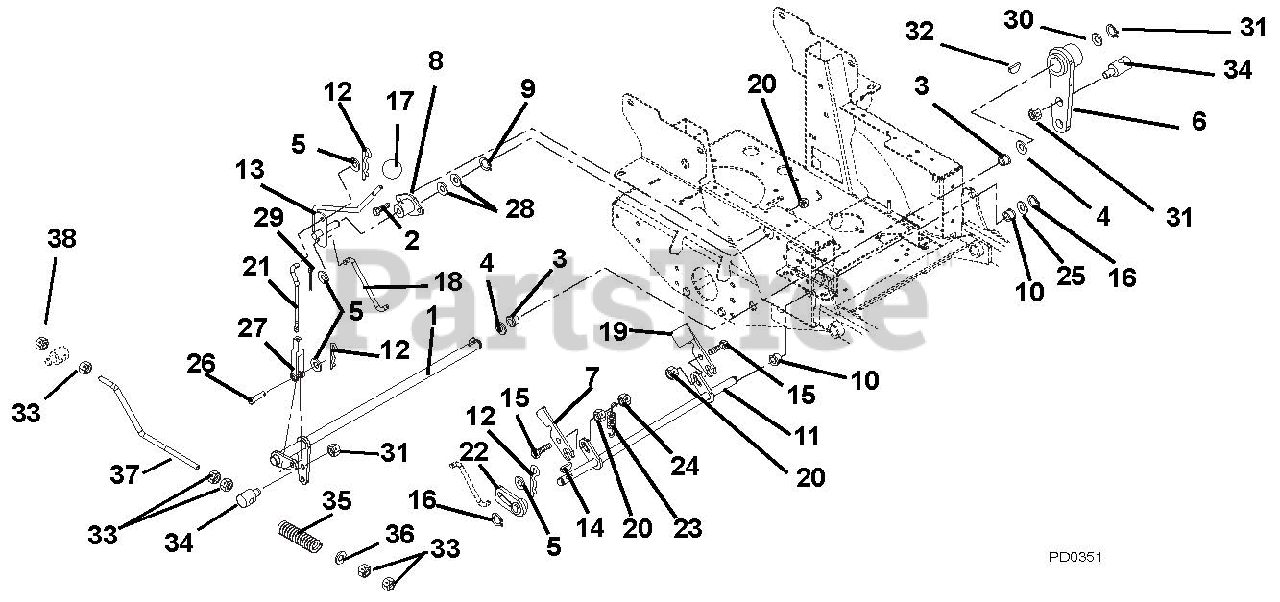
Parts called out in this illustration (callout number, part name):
1	Weldment, Brake Pivot
2	Bolt, Hex .31-18 x 1.00 Grade 5
3	Bushing, Flange .762 x 1.00 x .58 x 1.48 Nylon
4	Washer, Flat Steel .812 x 1.50 x .135
5	Washer, Flat Steel .406 x .812 x .065
6	Weldment, Brake Arm
7	Slide, Interlocking Brake
8	Bushing, Flange
9	Ring, Retaining External .625 x .05
10	Bushing, Flange .50 x .75 x .75 x 1.00
11	Weldment, Mechanical Brake
12	Pin, Hair
13	Weldment, Brake Actuating
14	Key, Woodruff .13 x .63
15	Bolt, Round Head Square Neck .31-18 x 1.25 Grade 5
16	Ring, Retaining External .50 x .05
17	Knob, Steering Lock
18	Linkage, Brake Actuating
19	Interlock, Safety Switch
20	Nut, Nyloc Flange 5/16-18
21	Linkage, Brake Compact-Z
22	Weldment, Parking Brake Hub
23	Spring, Tension .061 x .50 x 3.0
24	Nut, Locking Center .31-18
25	Washer, Flat Steel .505 x 1.00 x .062
26	Pin, Clevis .38 x 1.25
27	Clevis, .38-24 Adjustable
28	Washer-Flat-Steel .630 x 1.250 x .062
29	Pin, Cotter .09 x .75 Extended Prong Square Cut
30	Washer-Flat-Steel .755 x 1.375 x .062
31	Nut, Center Lock Jam Nut, .31-18
32	Key-Woodruff .19 x .75
33	Nut, Jam .375-24
34	Pin, Pivot
35	Spring, Compression .143 x .710 x 2.00
36	Washer, Flat Steel .406 x .812, .065
37	Linkage, Brake
38	Nut, Locking Center .375-24
